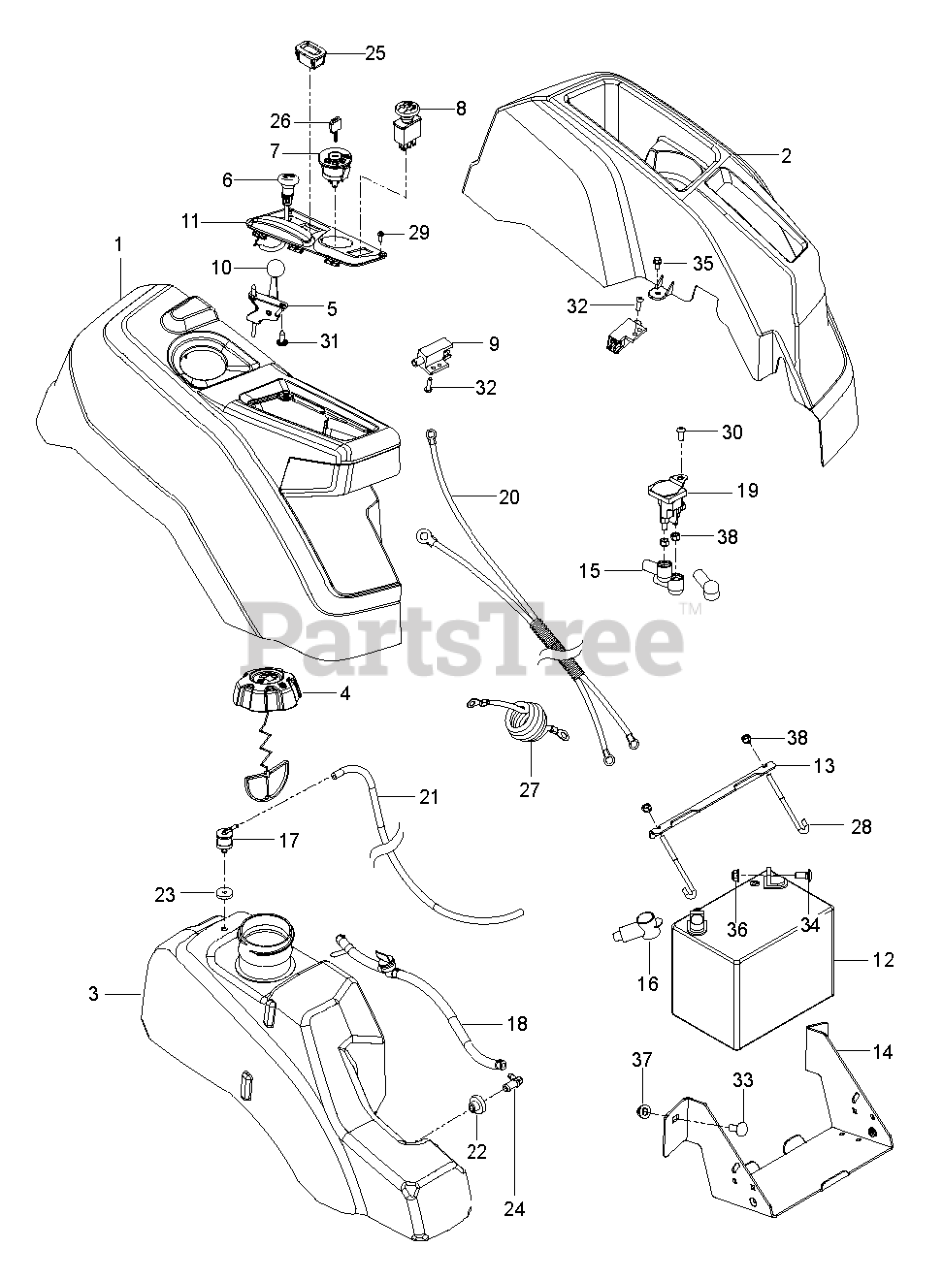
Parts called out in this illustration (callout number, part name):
1	CONSOLE.ASSY.RZ.REFRESH.RH
2	CONSOLE.LH.ASM
3	ASM.FUEL.TANK.LG.3".W/O SHIELD
4	FUEL CAP
4	CAP ASSY FUEL 3" GRAY
5	THROTTLE CABLE
6	CHOKE.PUSH-IN.STYLE
7	RP IGNITION SWITCH
8	RP SWITCH.PTO.TERMINAL.STD.RED
9	SWITCH.INTLK.RZ.RFRSH.BUTTON
10	KNOB.ROUND.BALL.BLACK
11	CONTROL.PANEL.RZ.REFRESH.RH
12	BATTERY, 12 V 330 AMP
13	BRACKET.PNT.MOUNT.BATTERY.EDIP
14	BOX.PNT.BATTERY.RZ.EDIP
15	TERMINAL COVER
17	VALVE.FUEL.CHECK
18	FUEL.HOSE.SHUT.OFF.ASM.10".18"
19	SOLENOID.STARTER.BRASS.PLUNGER
20	HARNESS.BTTRY.CABLE.RZ.REFRESH
21	HOSE.3/16".VAPOR.LINE.50"LGTH
22	BUSHING OUTLET T
23	GROMMET.ROV.SENTEC
24	STEM FUEL TANK
25	GUAGE.SRVCMNDR.HRMTR.
26	KEY MLD GEN DELTA
27	CABLE BATTERY POS RZ
28	HOOK.J.BATTERY
29	SCREW 6-19X.437
30	SCR 1/4-20 X 5/8 BTN SKT HD ZD
31	SCREW.PAN.HEAD.#10
32	SCREW.BUTTONHD.10-24X1/2.(2 2)
33	RHSNB 3/8C X 1
34	RP BOLT 5/16-18 X3/4 ZN/YEL GR
35	SCREW
36	5/16-18 NYLOC FLANGE NUT
37	NUT 3/8-16 HEX FLG NYLOC ZD
38	NUT.1/4-20.HEX.NYLOC.ZD
